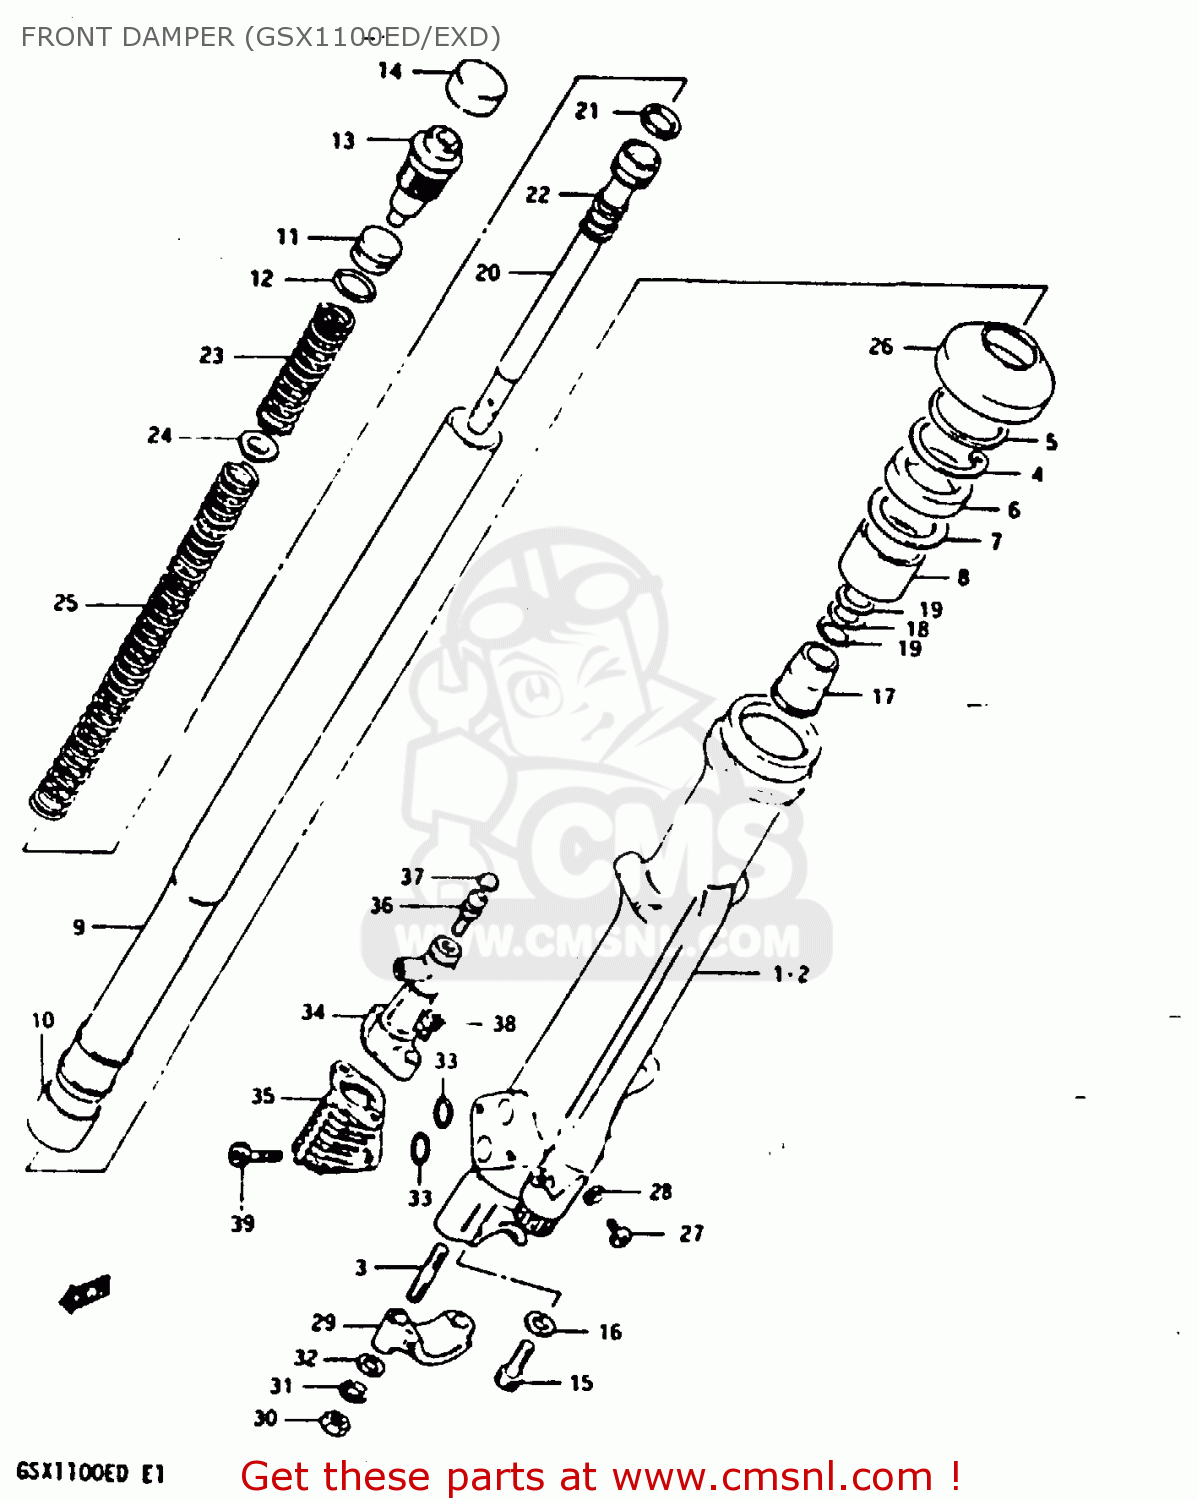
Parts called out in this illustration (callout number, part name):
1	OUTER TUBE, RH
2	OUTER TUBE, LH
3	STUD 8X30
4	RING,STOPPER
5	WASHER. FRONT FORK
6	OIL SEAL,FRONT FORK
7	WASHER
8	METAL,SLIDE
9	INNER TUBE
10	METAL,FRONT FORK PISTON
11	PISTON,FREE
12	O-RING
13	CAP
14	CAP,RUBBER
15	BOLT,FORK CYLINDER(10X25)
16	GASKET (NAS)
17	PIECE,OIL LOCK
18	WASHER
19	SPRING,LEAF
20	CYLINDER
21	RING,PISTON
22	SPRING,FORK REBOUND
23	SPRING
24	GUIDE,FRONT FORK SPRING
25	SPRING
26	SEAL,DUST
27	SCREW
28	GASKET,DRAIN,PLUG (NAS)
29	HOLDER,AXLE
30	NUT (8MM)
31	LOCK WASHER
32	WASHER
33	O RING
34	PLANGER SET,MODULATOR
35	VALVE SET,MODULATOR
36	BREATHER,AIR
37	CAP,BREADER
38	BOLT, MODULATOR (5X12)
39	BOLT,FRONT FORK
